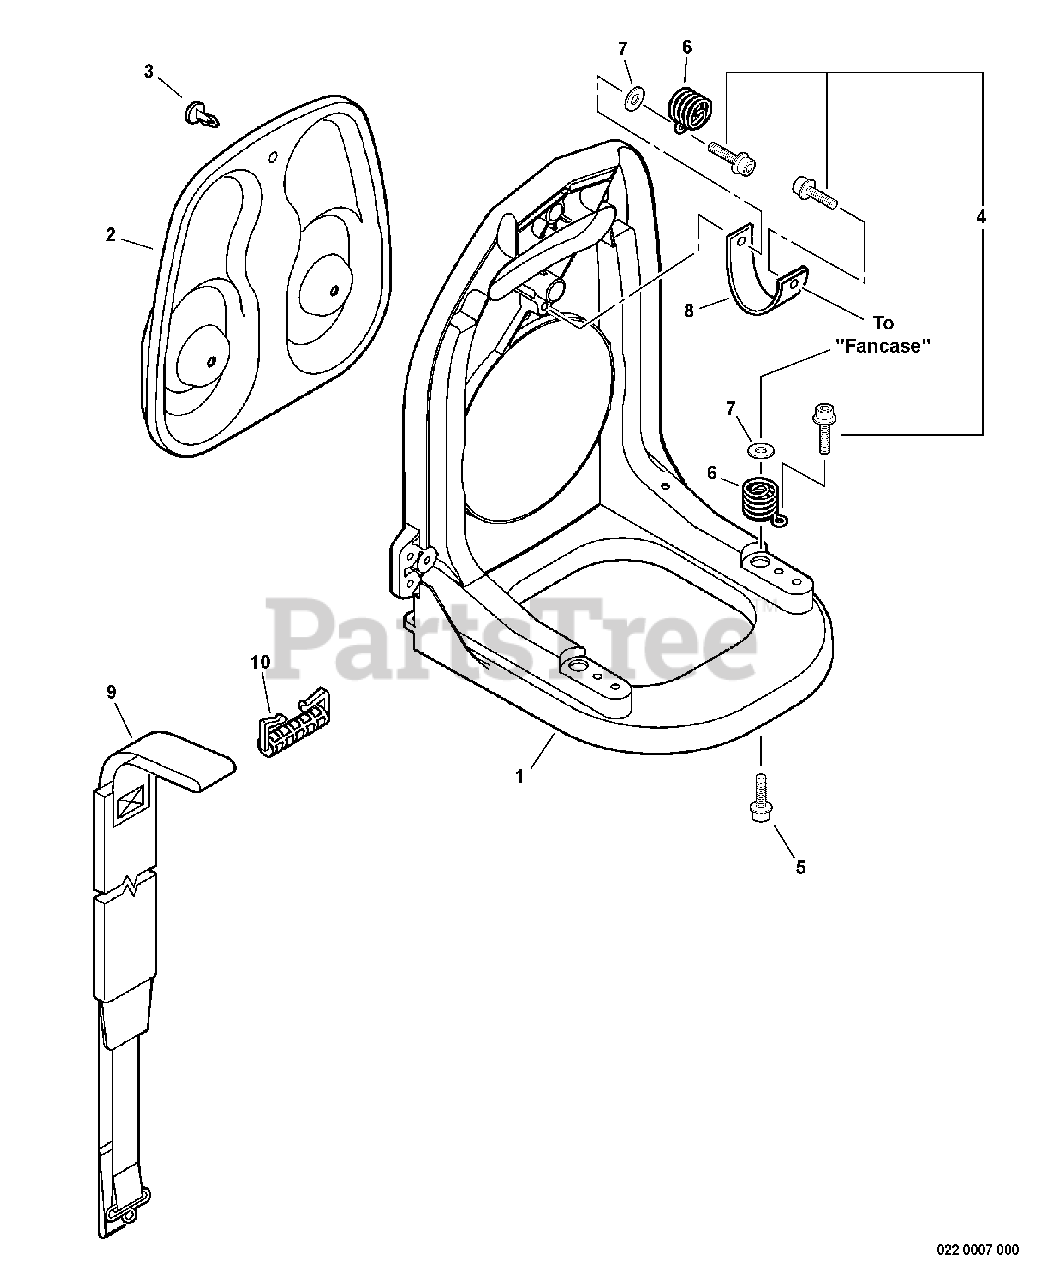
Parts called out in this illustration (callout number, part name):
1	FRAME, BACKPACK
2	CUSHION, BACKPACK
4	BOLT 5×20
5	BOLT 5×14
6	SPRING, COMPRESSION
7	WASHER 5.5×16×2T
8	STRAP, SAFETY
9	HARNESS ASSY
10	CLIP, HARNESS
